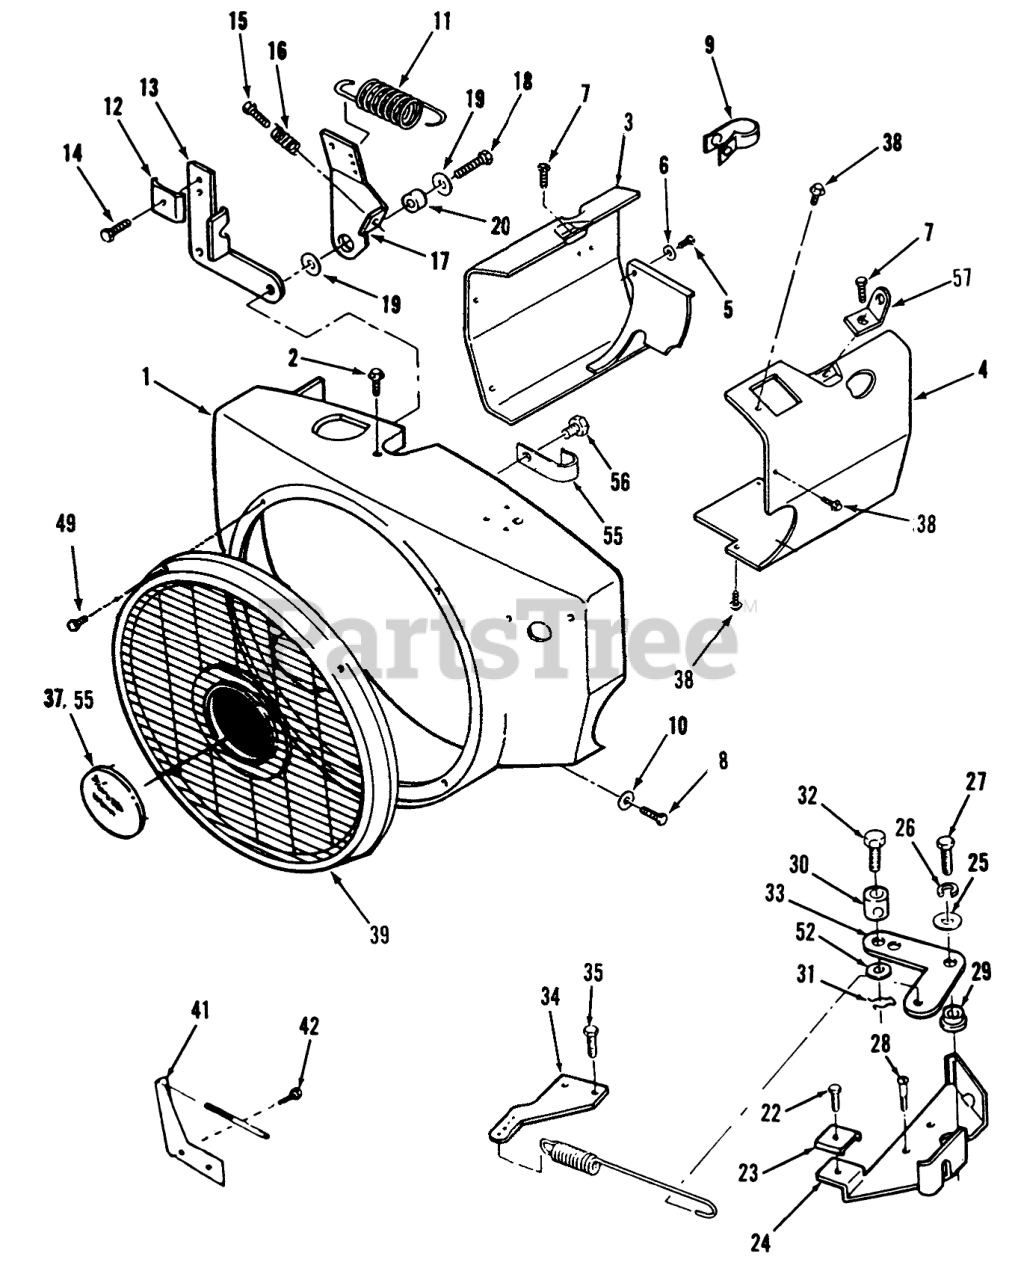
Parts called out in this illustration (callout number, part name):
1	BLOWER-HOUSING
2	HEX HD CAPSCREW
3	CYLINDER AIR HSG L H
4	Housing, Cylinder Air-RH
5	SCREW-HH
6	WASHER-FLAT
7	SCREW-HWH
8	SCREW-HH
9	Clamp
10	WASHER-FLAT
11	SPRING
13	Bracket-Cable
14	SCREW-TAPPING
15	SCREW-TAP
16	SPRING
17	Arm, Governor Control Without Swivel-Zinc Plated
19	WASHER-FLAT
20	BUSHING
22	SCREW-HWH
24	BRKT-GOVERNOR CONTRL
25	WASHER-FLAT
26	Washer-Lock
27	Bolt
28	HEX HD CAP SCREW
29	BUSHING-GOV CONTROL
30	BUSHING
31	PIN-COTTER
32	Bolt
33	LINK-GOV CONTROL
34	ADAPTER-GOV ARM
35	SCREW-TAPPING PAN HD
37	Plug
38	SCREW-HWH
39	GUARD-STATIONARY
41	BRACKET
42	SCREW-HWH
48	SCREW - THREAD CUTTING
49	SCREW-PAN HEAD
55	CLIP-WIRE
56	SCREW-HWH
57	BRACKET-LIFTING
